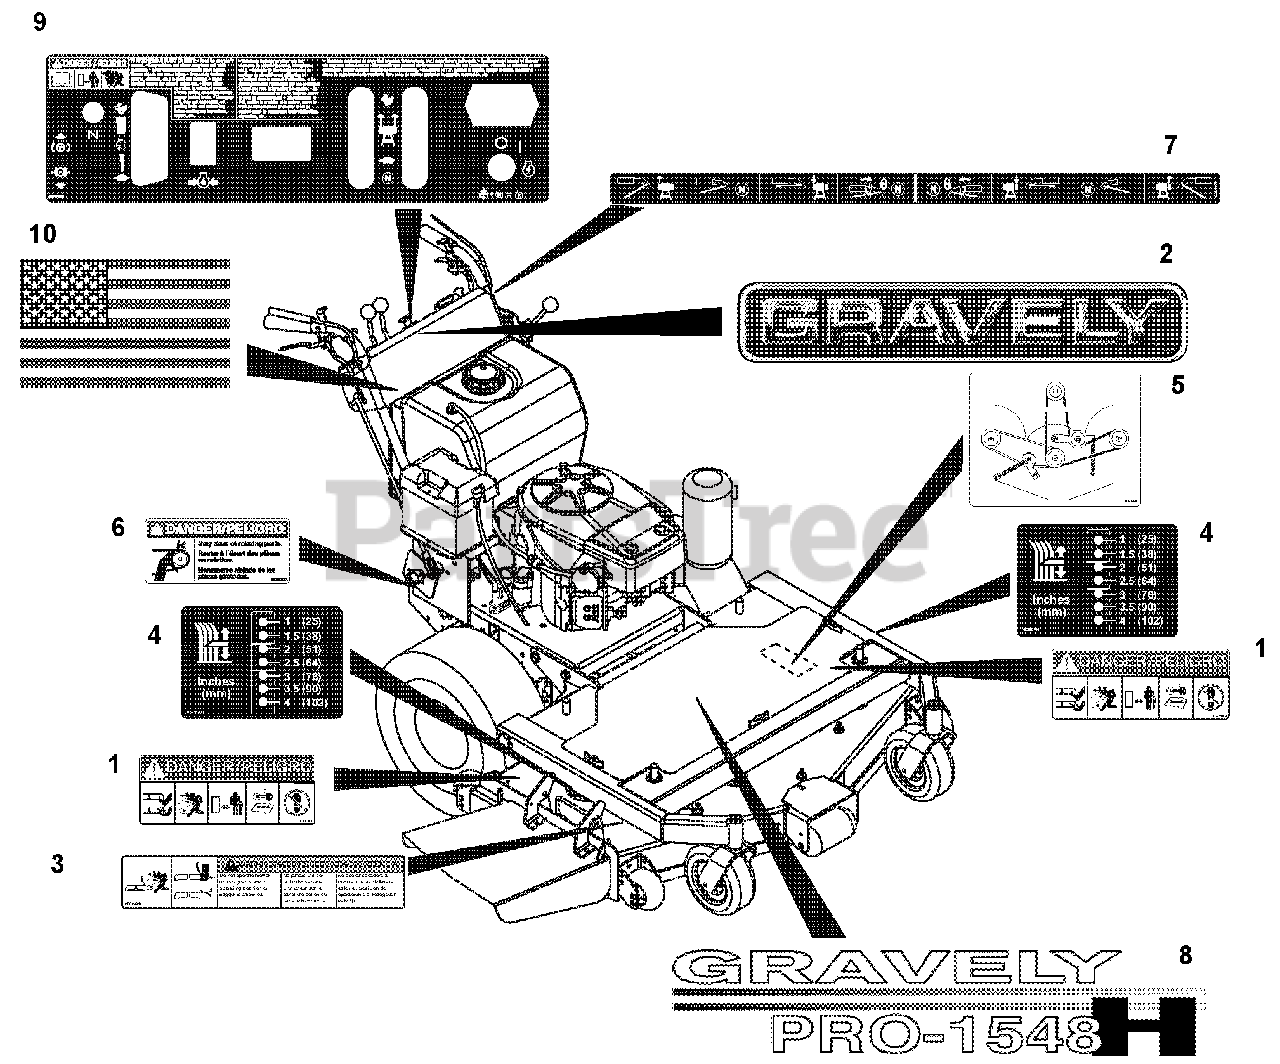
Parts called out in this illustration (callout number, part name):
1	Decal, Mower Pan Head Danger
2	Decal- 15" Gravely Logo
3	Decal, Warning
4	Decal-Height of Cut- Floating
5	Decal-Belt Diagram-3 Spindle
6	Decal-Danger-Belt Rotating
7	Decal, Steer Levers (107, 108, 109)
8	Decal-Pro 1548H (107, 116)
9	Decal, Control HE17 (108, 109)
10	Decal, American Flag
